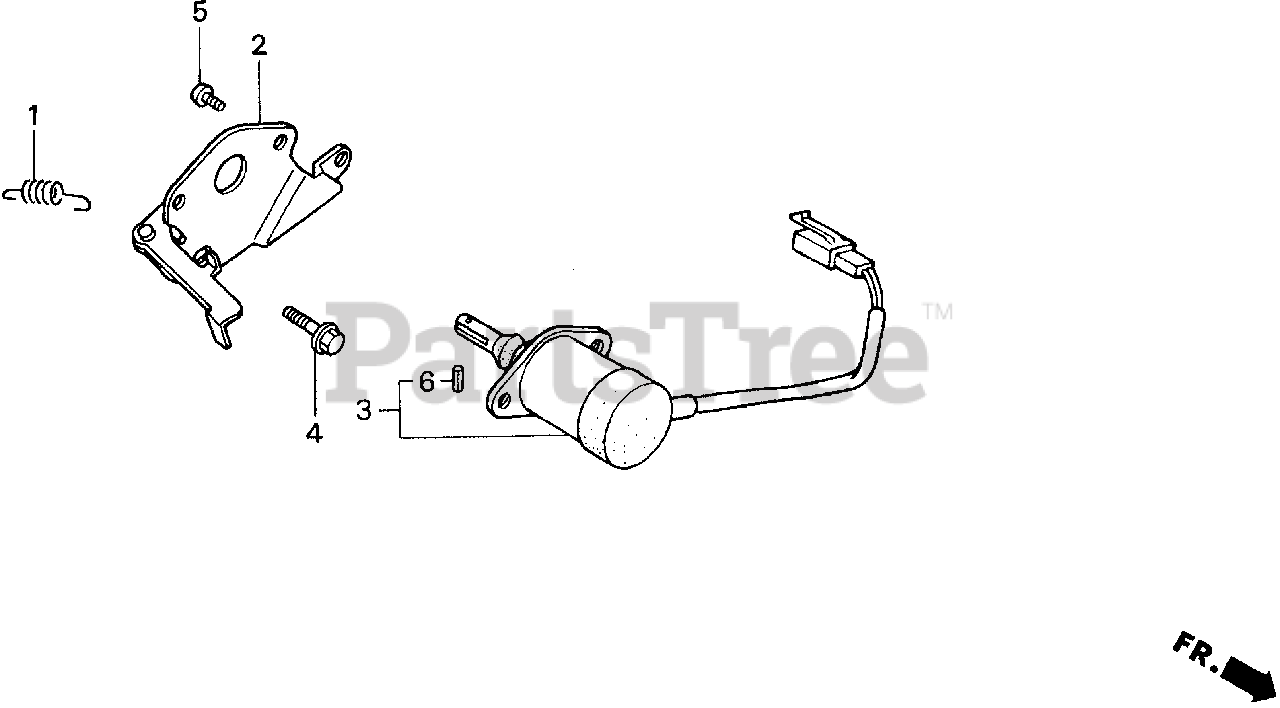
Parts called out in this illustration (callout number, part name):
1	SPRING, CHOKE RETURN
2	LEVER, THROTTLE
3	SOLENOID ASSY.
4	BOLT, FLANGE (6X12) (CT200)
5	SCREW, PAN (5X8)
6	PIN, SPRING (2.5X16)
